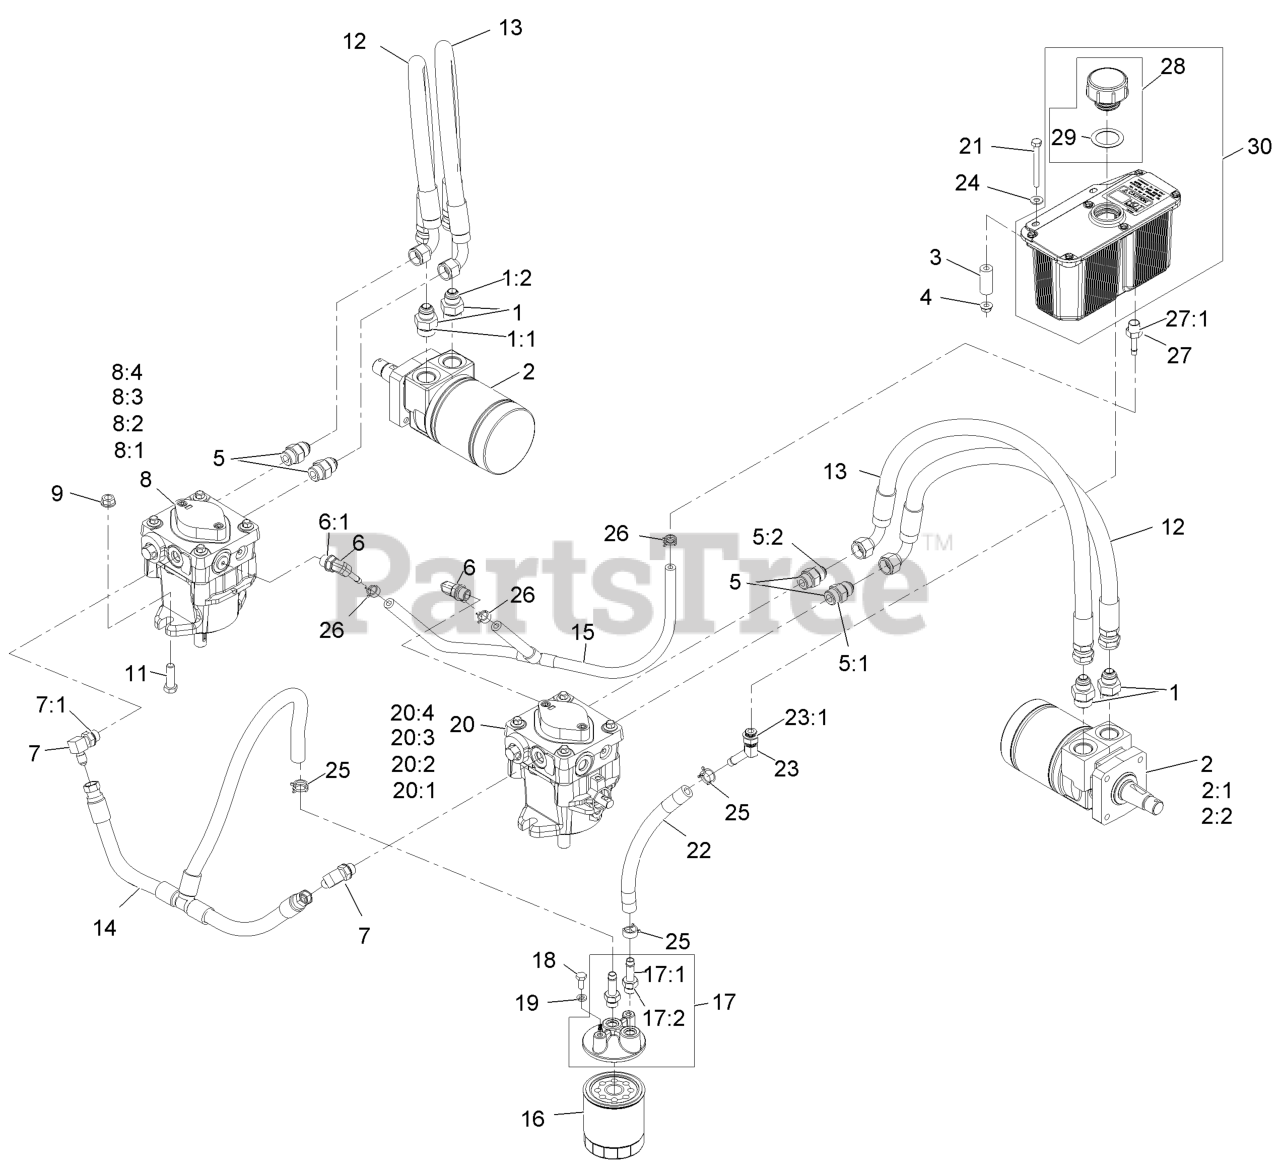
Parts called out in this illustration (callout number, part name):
1	FITTING-STRAIGHT
2	HYD MOTOR ASM
2:1	BEARING AND SEAL KIT
2:2	SEAL KIT
5	FITTING-STRAIGHT
6	ELBOW-90 DEG
7	FITTING-ELBOW, 90 DEG
8	LH HYD PUMP ASM
8:1	INPUT SHAFT KIT
8:2	BEARING-THRUST
8:3	CYLINDER BLOCK KIT
8:4	SEAL OVERHAUL KIT
9	NUT-FLANGE
11	SCREW-HH
12	HYD HOSE ASM
13	HYD HOSE ASM
14	CHARGE HOSE ASM
15	CASE DRAIN HOSE ASM
16	FILTER-25 MICRON, BI-DIRE
16	ELEMENT-FILTER, WINTER
17	FILTER HEAD ASM
17:1	ADAPTER-STRAIGHT
18	SCREW-HH
19	WASHER-LOCK
20	RH HYD PUMP ASM
20:1	INPUT SHAFT KIT
20:2	BEARING-THRUST
20:3	CYLINDER BLOCK KIT
20:4	SEAL OVERHAUL KIT
21	SCREW-HH
22	HOSE-CHARGE
23	FITTING-BARBED, 45 DEG
24	WASHER-FLAT
25	CLAMP-HOSE
26	CLAMP-HOSE
27	ADAPTER-STRAIGHT
28	KIT,HYD RES CAP W/GASKET
29	GASKET-CAP
30	HYD RESERVOIR ASM
